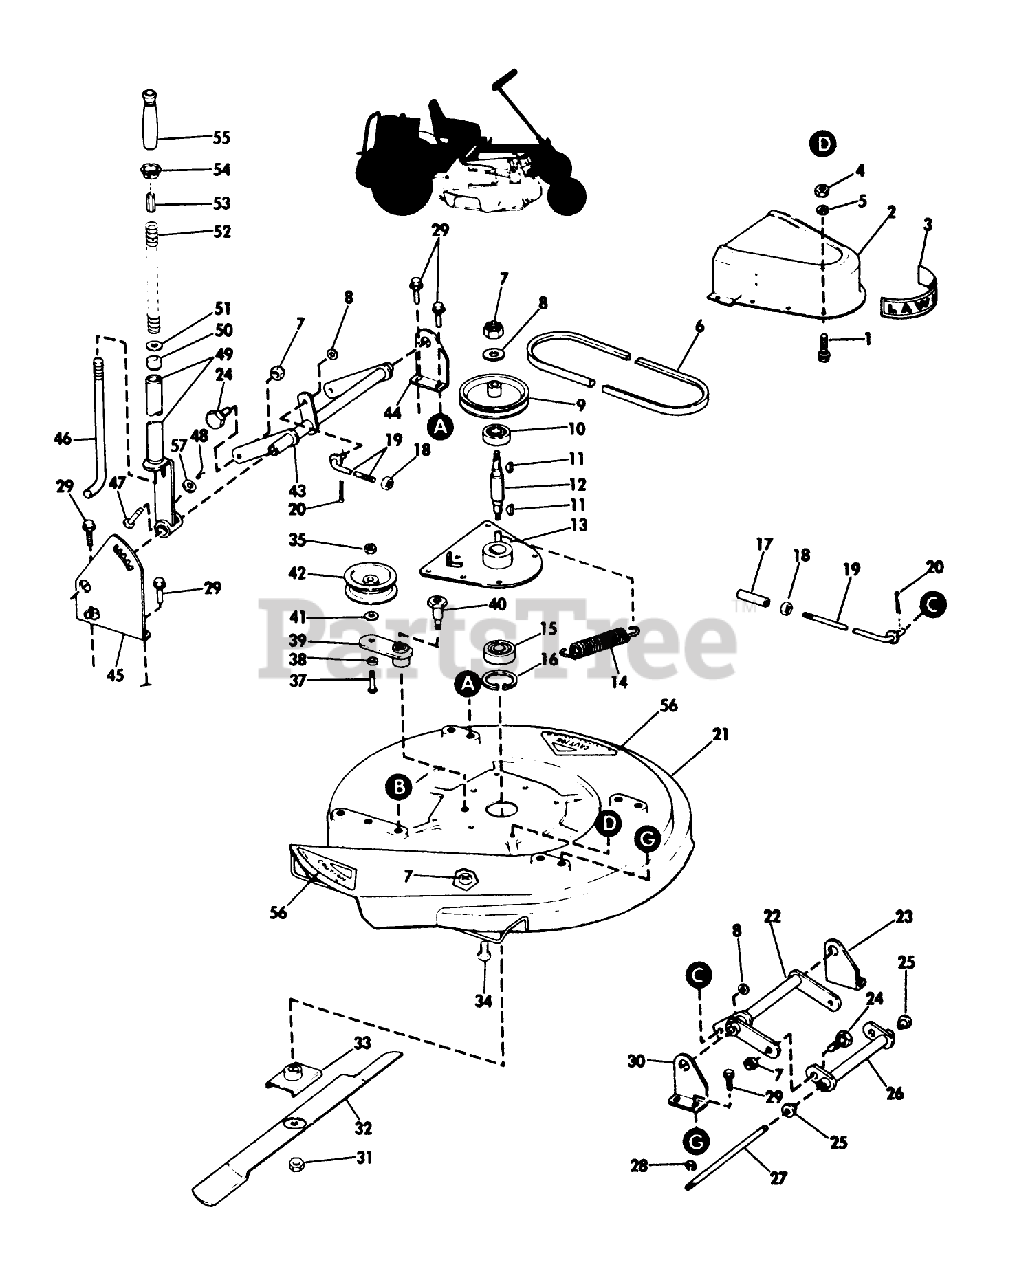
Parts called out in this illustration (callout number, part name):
4	Lockwasher
18	Jam Nut-Stabilizer Link Assembly
35	LOCKNUT
